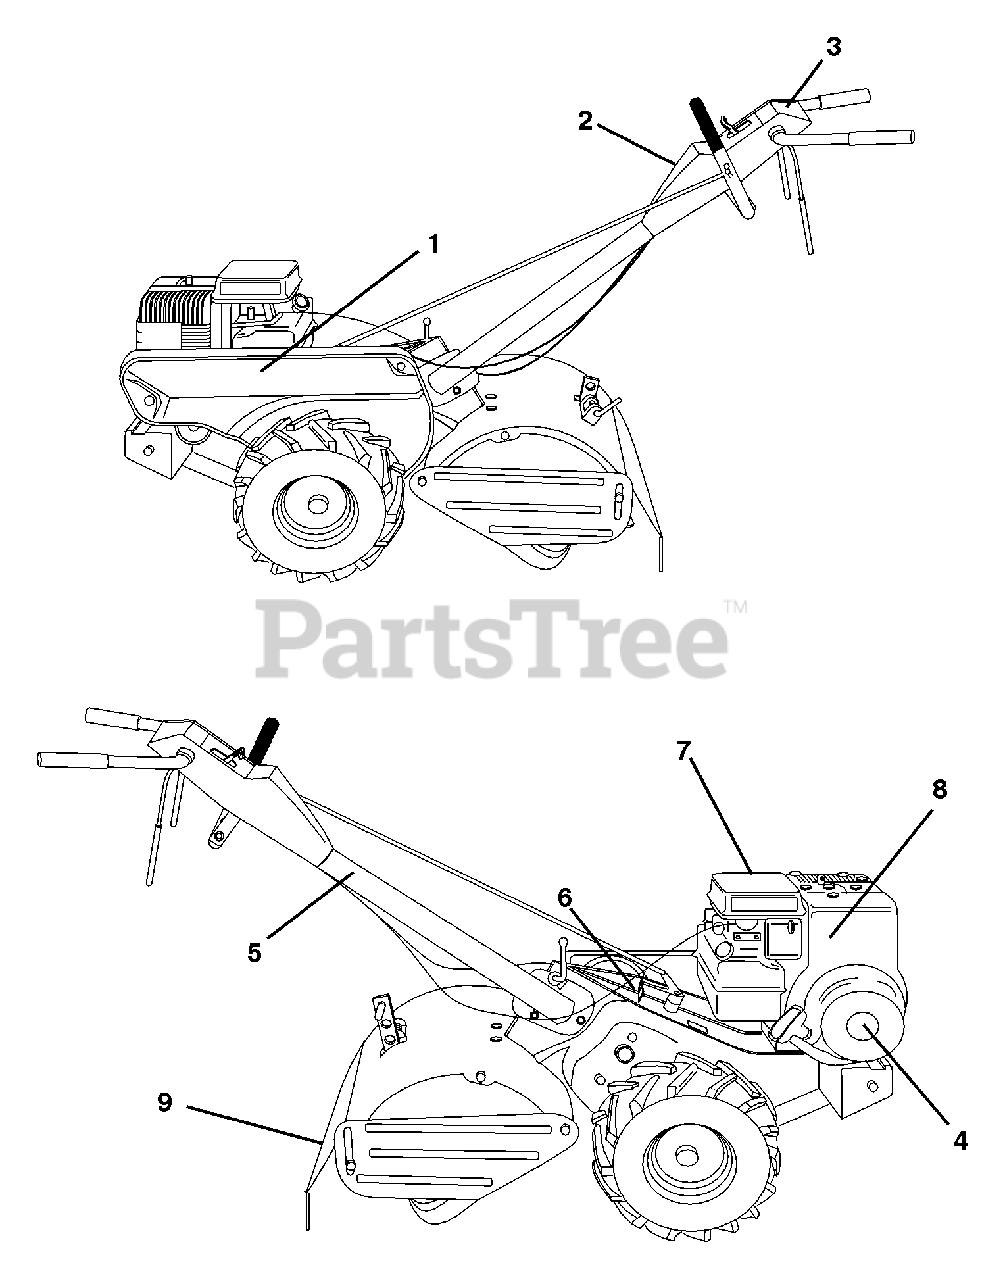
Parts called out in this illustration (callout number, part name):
1	Decal, Logo
2	Decal, Logo
3	Decal, Logo
4	Decal, 5 HP
5	Decal, Hand Placement
6	Decal, Shift Indicator
7	Decal, Warning
8	Decal, Briggs & Stratton
9	Decal, Warning, Rotating Tines
